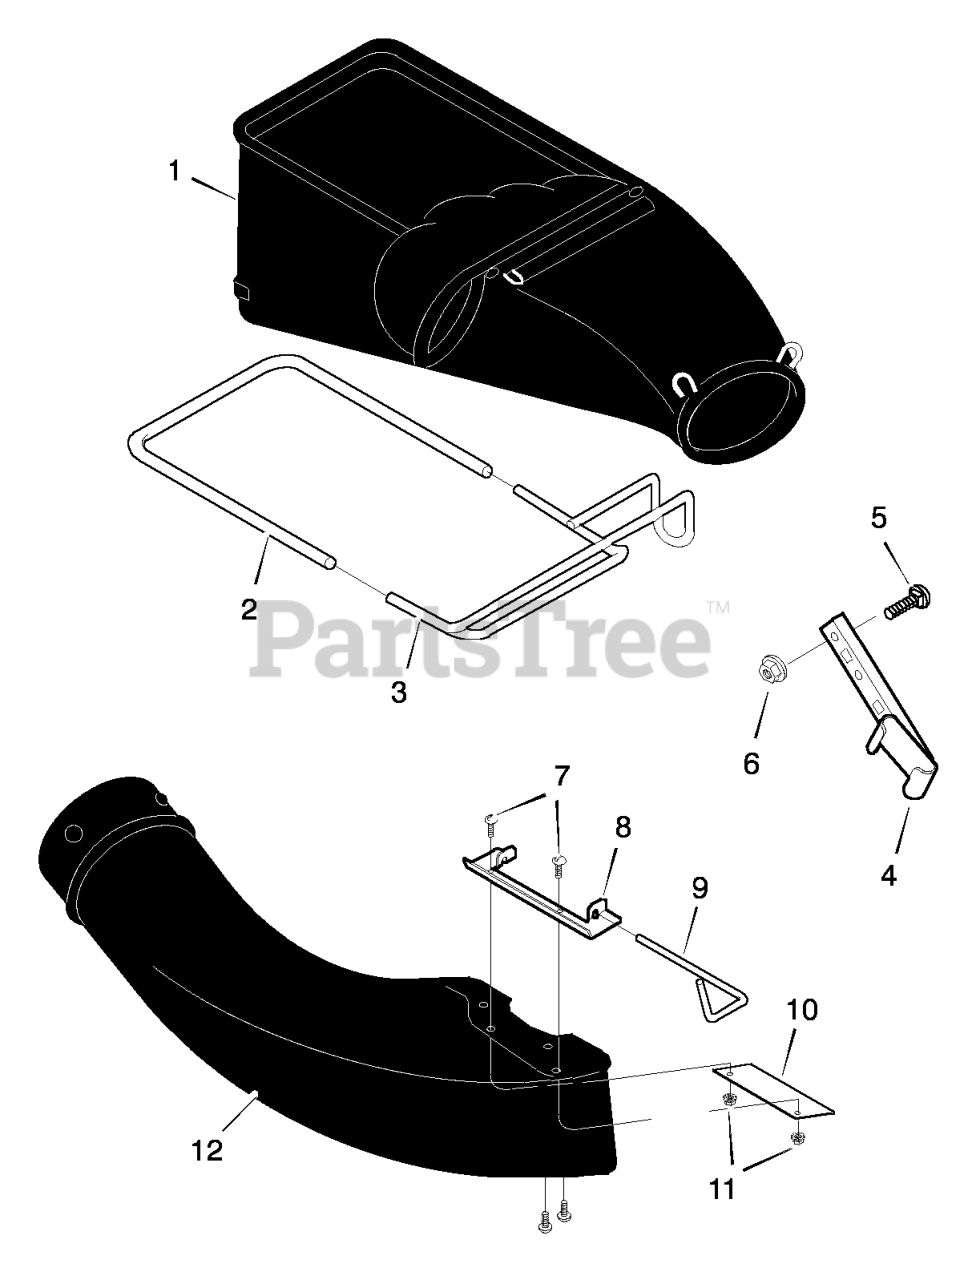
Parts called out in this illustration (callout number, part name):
1	Bag, Grass
2	Tube, Support
3	Frame, Bag
4	Bracket, Handle
5	Bolt, Carriage
8	Bracket, Chute
9	Pin, Locking
10	Plate, Inside
12	Extension, Chute
